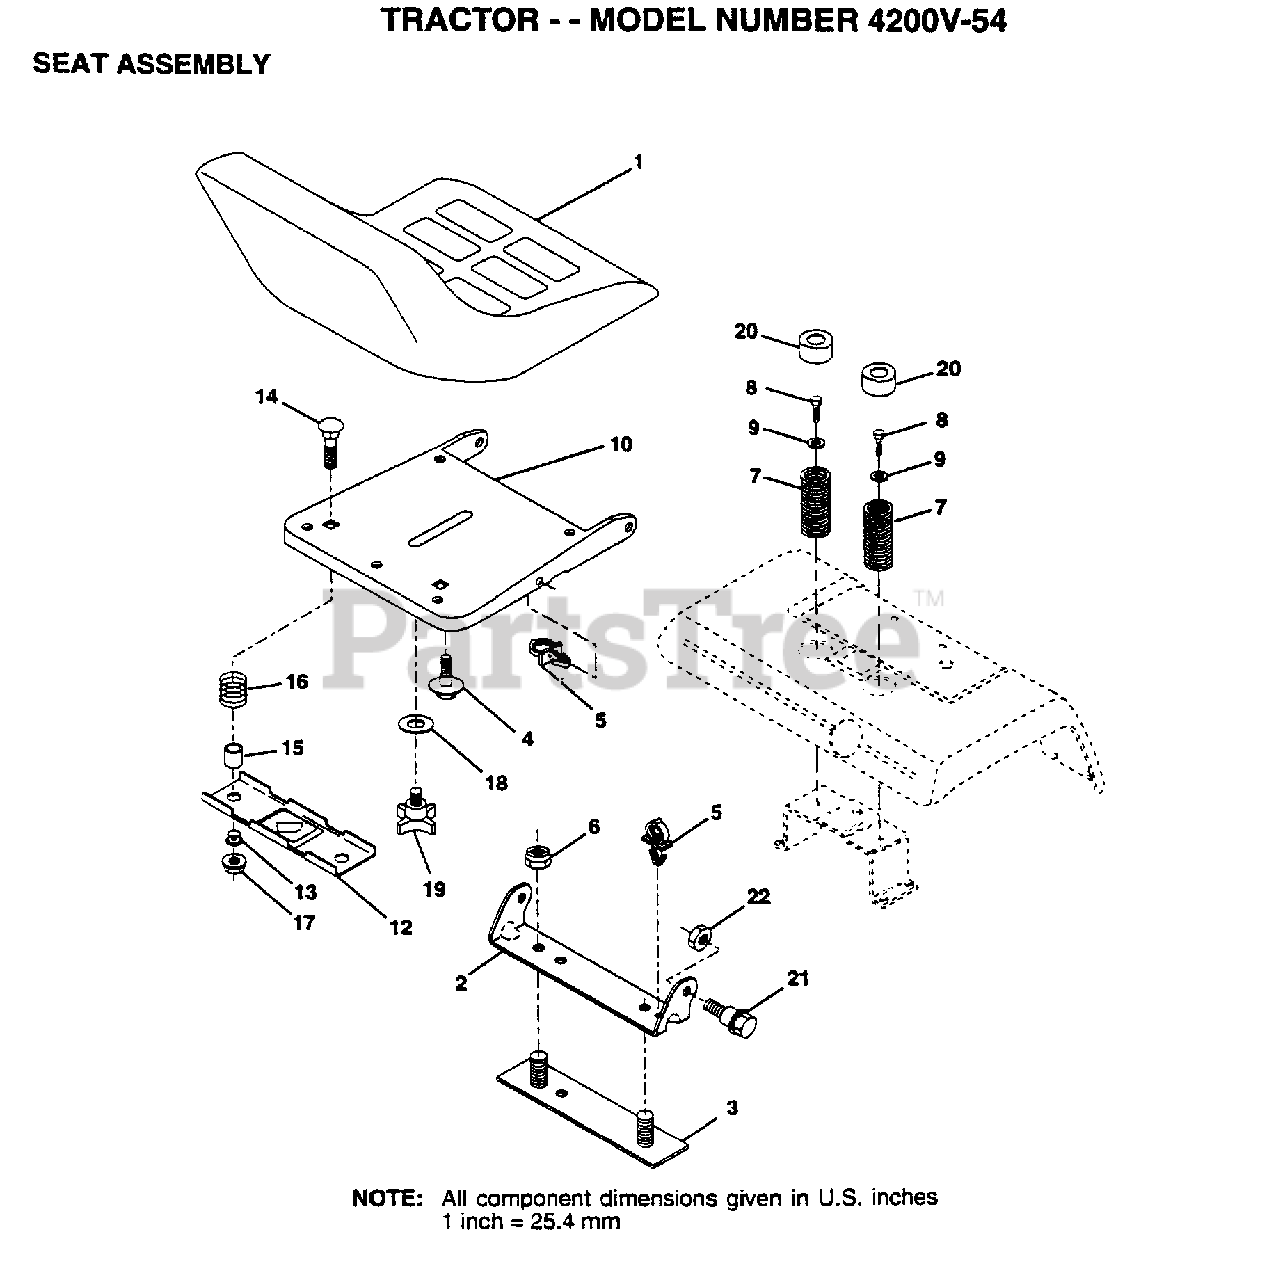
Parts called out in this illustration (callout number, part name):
2	BRACKET PVT SEAT
3	STRAP ASM FENDER
4	"BOLT,SHOULDER"
5	CLIP.PUSH-IN.HING
6	NUT
7	SPRING COMPRESSIO
8	SCREW LT
9	WASHER
12	BRKT SWITCH
13	BUSHING
15	SPACER SPLIT
16	SPRING COMPRESSED
18	WASHER
19	"KNOB 1/2"" YT"
20	CAP SPRING
21	BOLT.SHLD.5/16-18
